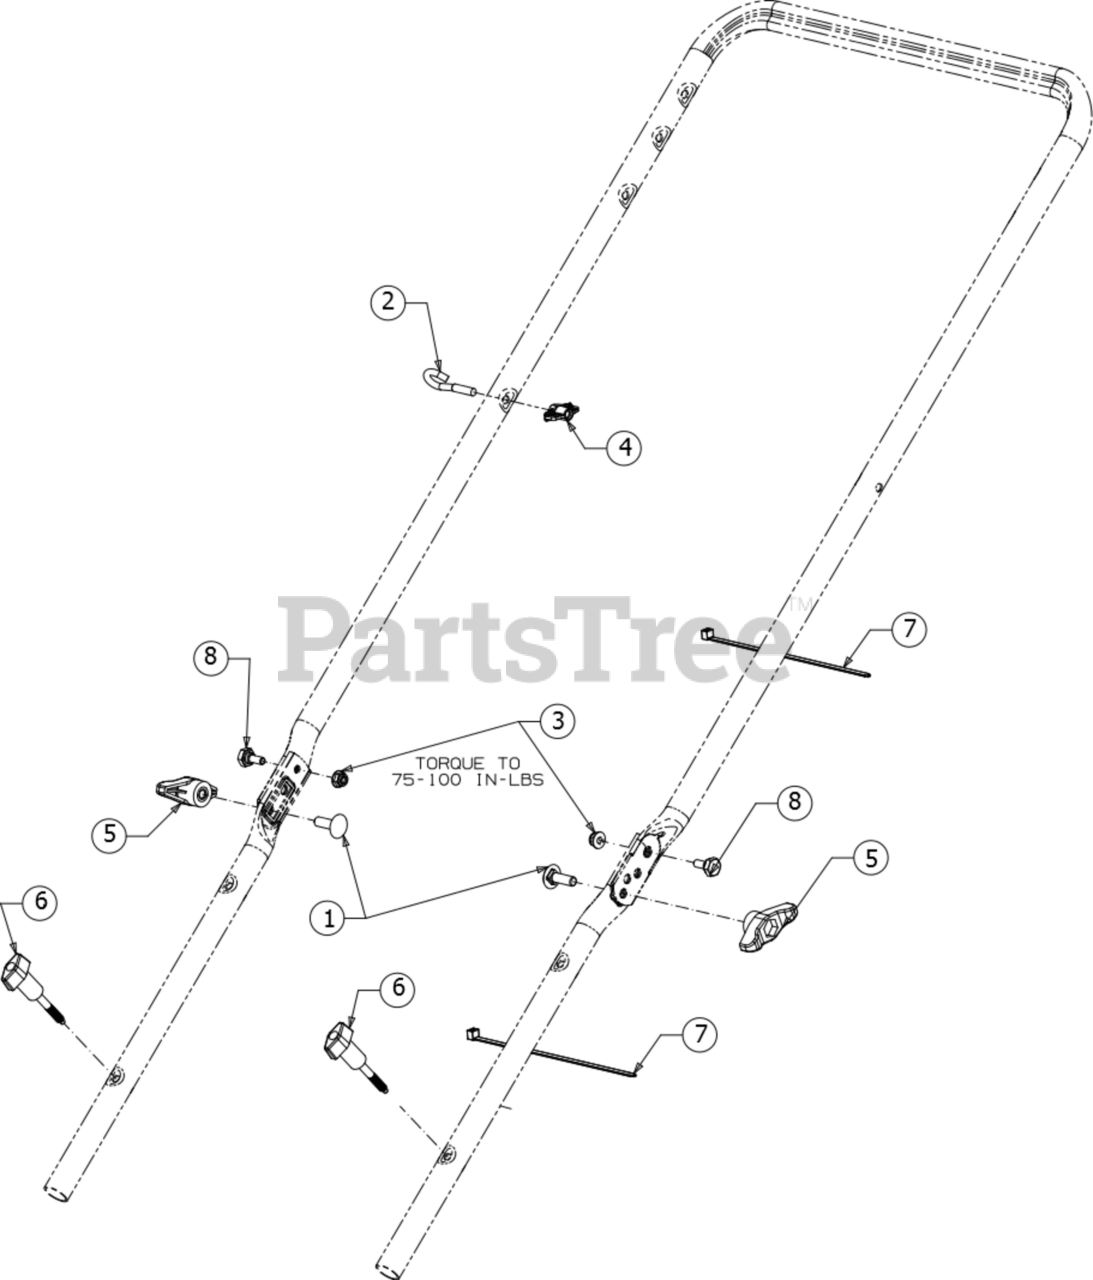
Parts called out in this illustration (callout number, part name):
1	SCREW 5/16-18 X 1.00 GR5
2	EYEBOLT 1/4-20
3	FLANGE LOCK NUT
4	HANDLE KNOB
5	WING KNOB 5/16-18
6	WING KNOB 1/4-20
7	CABLE TIE 7"
8	SHOULDER SCREW
